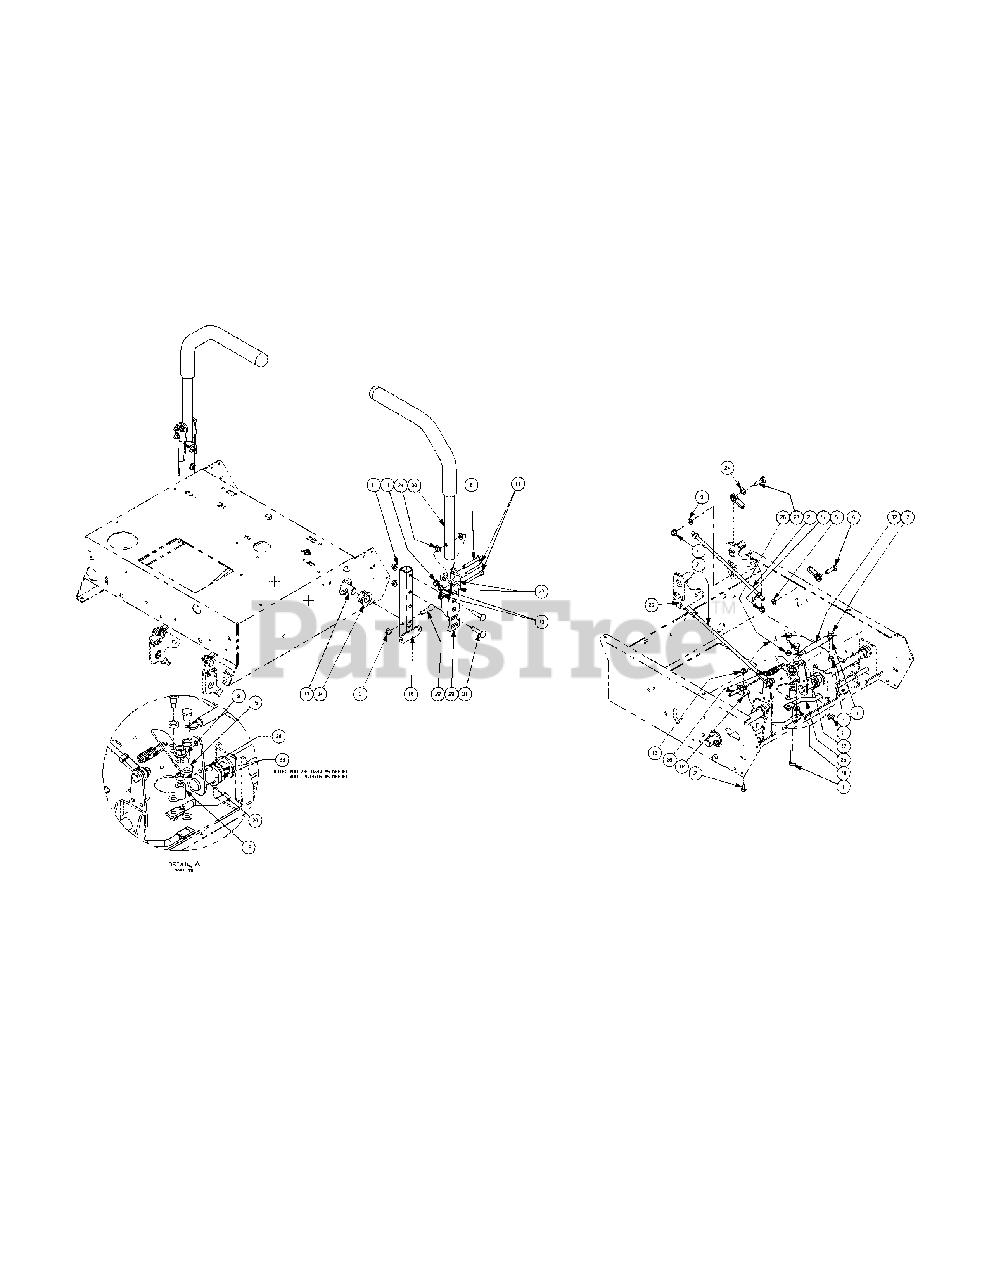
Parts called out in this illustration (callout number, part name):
1	Hex Cap Screw, 3/8-16 x 1-1/2
2	Hex Cap Screw, 1/4-20 x 1/2
3	Nylock Nut, 5/16-18
4	Hex Nut, 5/16-18
5	Flat Washer, 5/16
6	Hex Head Cap Screw, 5/16-18 x 1.00
7	Hex Cap Screw, 5/16-18 x 1-1/2
8	Hex Cap Screw, 5/16-18 x 2.00
9	Nut, Flange Lock, 3/8-16
10	Flat Washer, 1.4 x .630 x .0515
11	Nut, 5/16-18, Lock
12	Shoulder Screw, 1/4-28
13	Nut, 1/4-20, Hex Flange Lock Nut
14	Hex Cap Screw, 1/4-20 x 2.00
15	Brake Lever Plate
16	Pivot Bracket Weldment
17	Steering Input Shaft Assembly
18	Spacer, .385 ID x .625 OD x .869
19	Brake Cable Mounting Bracket
20	Spacer, .380 x .563 x .196
21	Steering Link Rod
22	Socket Head Capscrew, 5/16-18 x 1.25
23	HHCS, 5/16-18 x 1-1/4
24	Bushing, .310 x .172 x .688 x .06
25	Control Lock Rod
26	Control Cable Lock Out
27	Spacer, .25 ID x .38 OD x 1.13
28	Retainer Ring, E-Clip
29	Lapbar Pivot Bracket
30	Lapbar Assembly includes:
31	Carriage Bolt, 5/16-18 x 1.50
32	Extension Spring, .53 OD x 4.7
33	Flat Washer, .793 ID x 1.24 OD x .060
34	Hex Flange Bearing, .752 ID
